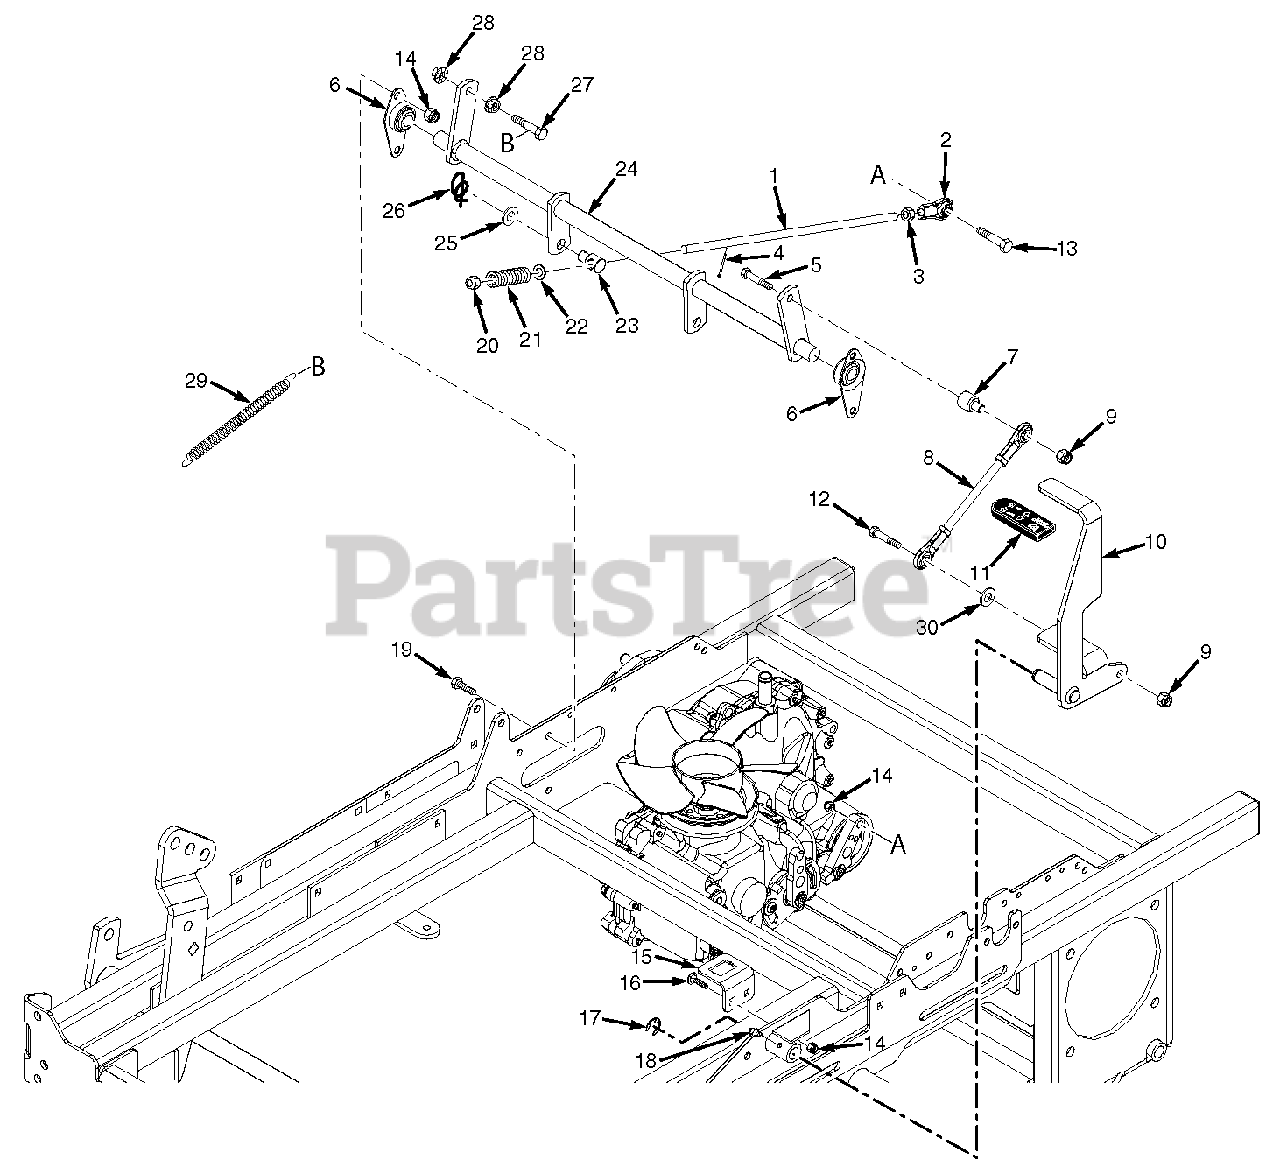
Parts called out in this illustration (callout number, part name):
1	Link, Lower Brake
2	Rod End, 3/8-24
3	Nut, Jam 3/8-24 UNF
4	Cotter Pin
5	Bolt, Hex Head 3/8-16 x 2-3/4"
6	Bearing, Self Align
7	Pivot
8	Linkage, Upper Brake
8	Rod End, 3/8-24 RH
8	Nut, Jam 3/8-24 UNF
8	Rod End, 3/8-24 LH
8	Nut, Jam 3/8-24 UNF LH
9	Nut, Elastic Stop 3/8-16
10	Brake Lever w/Grip
11	Grip, Brake Lever
12	Bolt, Hex Head 3/8-16 x 1-1/2"
13	Bolt, Hex Head 3/8-16 x 2"
14	Nut, Flange Head Elastic Stop 5/16-18
15	Bracket, Brake Switch
16	Bolt, Carriage 5/16-18 x 3/4"
17	Retaining Ring, .625 External "E"
18	Grease Fitting, 1/4-28 Self Tap
19	Bolt, Hex Head 5/16-18 x 3/4"
20	Nut, Elastic Stop 3/8-24
21	Spring
22	Flatwasher, 3/8-.406 x .734 x .063
23	Bushing, Pivot
24	Weldment, Brake Linkage
25	Flatwasher, 3/8-.391 x .938 x .105
26	Pin, Rue Cotter 1/2" Dia.
27	Bolt, Hex Head 3/8-16 x 1-1/2"
28	Nut, Serrated Flange 3/8-16
29	Spring
30	Flatwasher, 3/8-.391 x .938 x .105 HD
